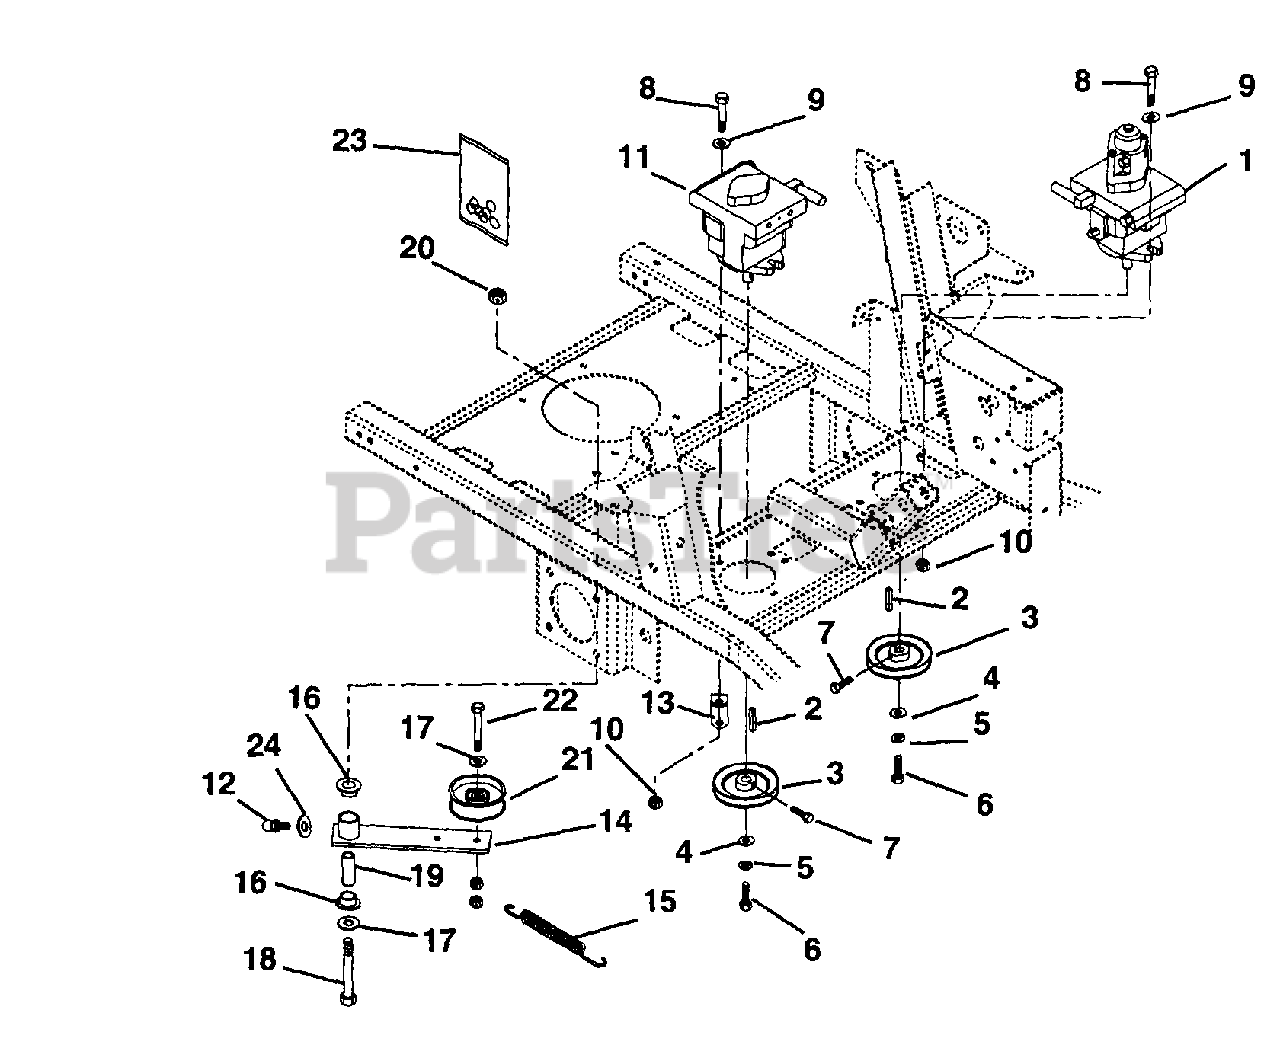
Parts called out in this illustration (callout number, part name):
1	HYDROSTAT BDP-10L-901P W/AUX
2	KEY-STR 5MMX25MMX5MM
3	SHEAVE, PUMP .592 X 4.345
4	WSHR-FL-STL .281X1.0X.048 YWZC
5	@WSHR-LK .25X.062 REG YWZC
6	BLT-HEX M6 X 1.0X12 YWZC
7	@BLT-HEX .25-20X.50 GR5 YWZC
8	@BLT-HEX .38-16X1.25 GR5 YWZC
9	WSHR-FL-STL .390X.75X.125 YWZC
10	@NUT-LK-CTR .38-16 YWZC
11	VARIABLE PUMP BDP-10L-117P
12	FTG-LUBE .25-28X.256 YWZC
13	ANCHOR, SPRING IDLER
14	IDLER ARM - GROUND DRIVE
15	SG-TENS .120 X .845 X 6.50
16	BSHG-FLG .762X1.0X.580X1.48 NY
17	@WSHR-FL-STL.531X1.06X.095YWZC
18	@BLT-HEX .50-13X3.00 GR5 YWZC
19	BUSH.,S.560X.745X2.04 ST
20	@NUT-LK-CTR .50-13 YWZC
21	IDLER, FLAT .377X4.0X.96W POLY
22	@BLT-HEX .38-16X2.25 GR5 YWZC
23	KIT, PUMP SEAL (P/N 2513018)
24	WSHR-FL-STL .265X.50X.087YWZC
